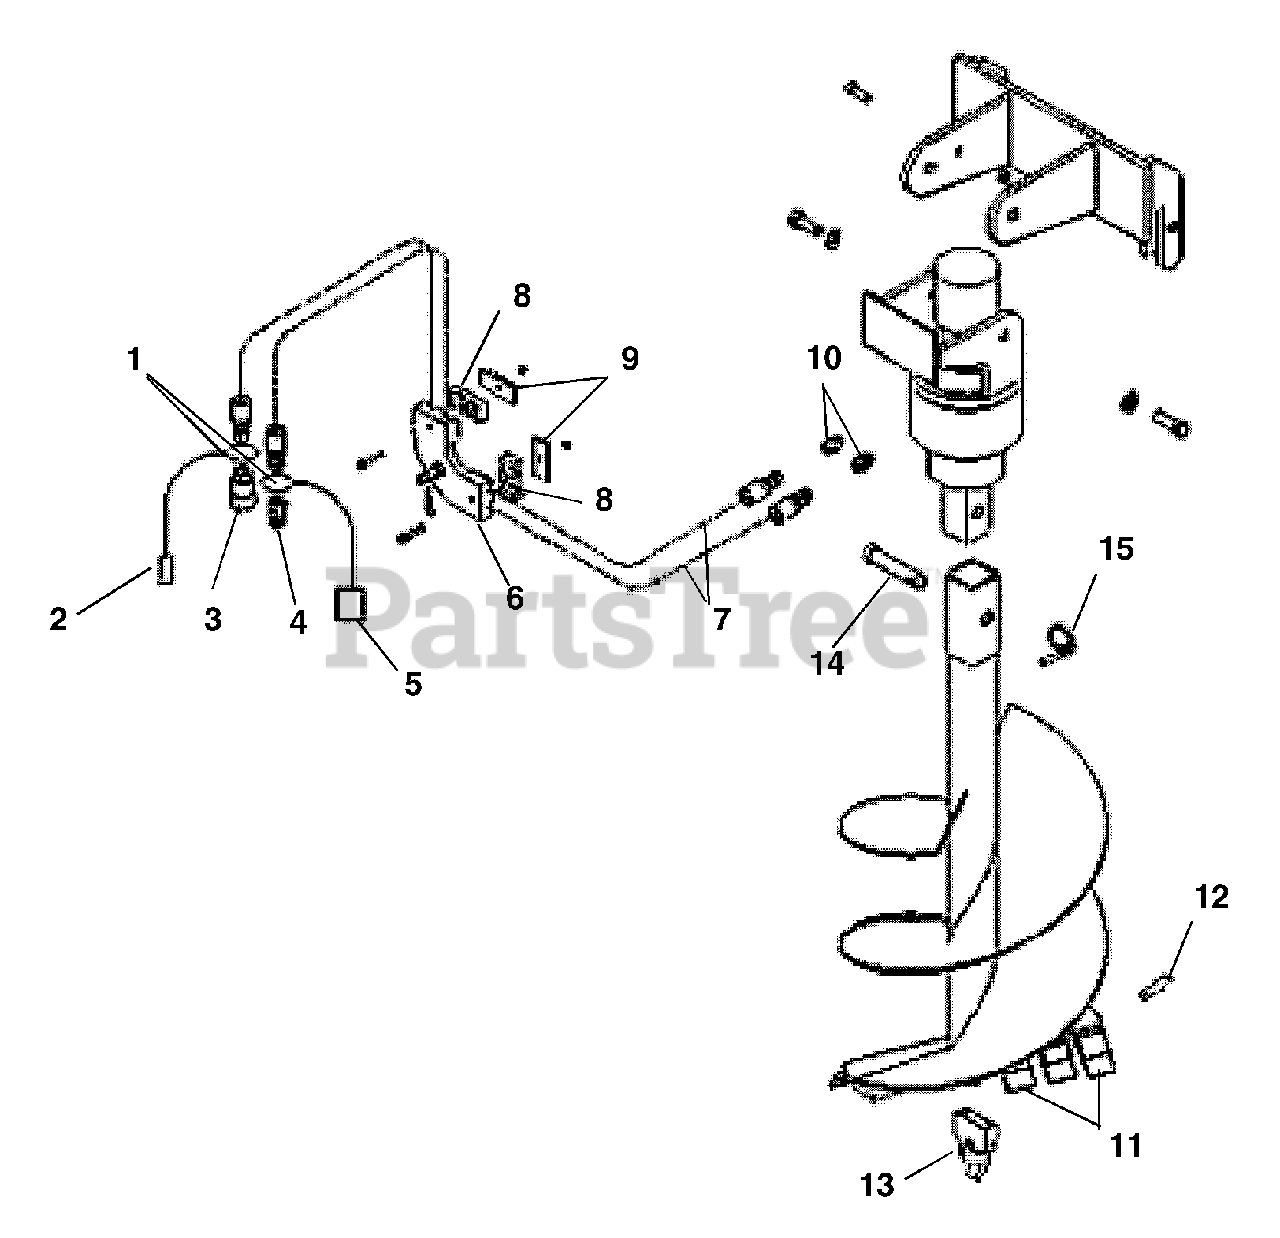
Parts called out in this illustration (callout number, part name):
1	SEAL, BONDED
2	PLUG, DUST .500
3	COUPLING, FML QCK .500-14 BSPP
4	COUPLER, MALE QCK .500-14 BSPP
5	CAP, DUST .500
6	BRACKET,ATTACHMENT HOSE -ASSY
7	HOSE, HYD
8	CLAMP, HOSE
9	PLATE, COVER (CPT-3)
10	FTG, HYD STR M8J-M10O
11	TOOTH, AUGER-PLAIN
12	LOCK, TOOTH-RUBBER 4 FT.LNGTH
13	00T, PILOT-CARBIDE
14	PIN-CLEV .875X4.500
15	PIN-W/RING .43 DIA X 1.50
